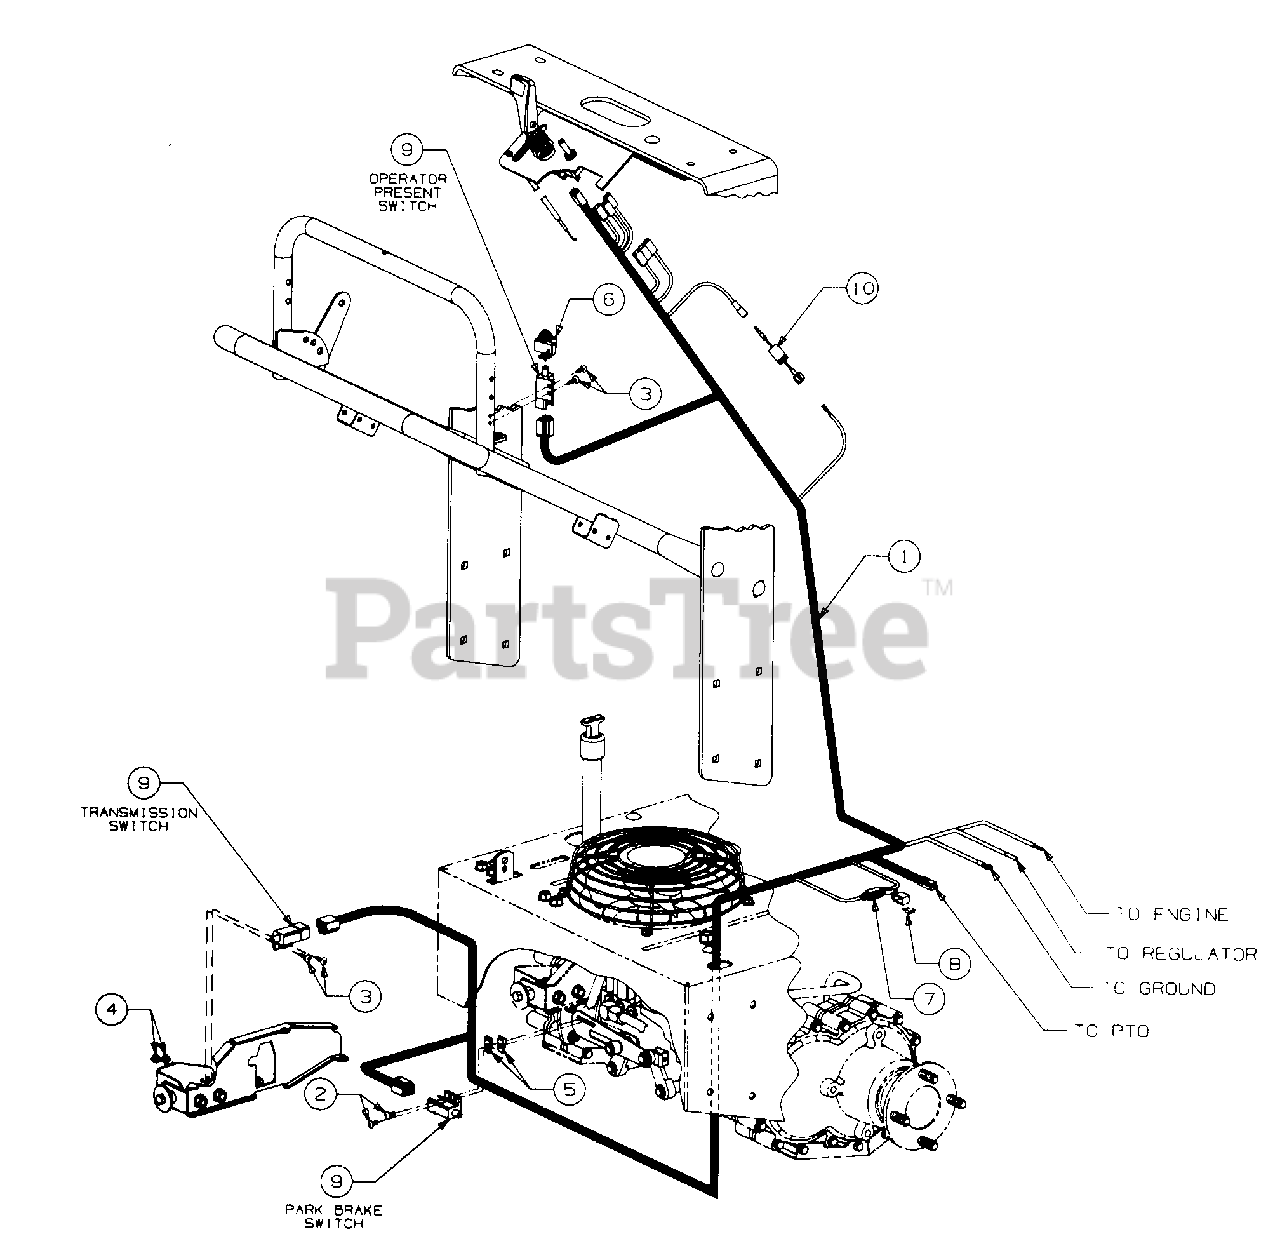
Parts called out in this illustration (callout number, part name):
2	Screw, Truss Mach, #10-24 X .50 Lg
3	Screw, Pan Hd Cutting, #10-24 X .75 Lg
4	Nut, Hex Lock, #10-24
5	Nut, Speed
6	Cover, Protective
7	Holder, Inline Fuse
8	Fuse, 20 Amp Mini
9	Switch, Double Poled Plunger
10	Capacitor, Clutch,
